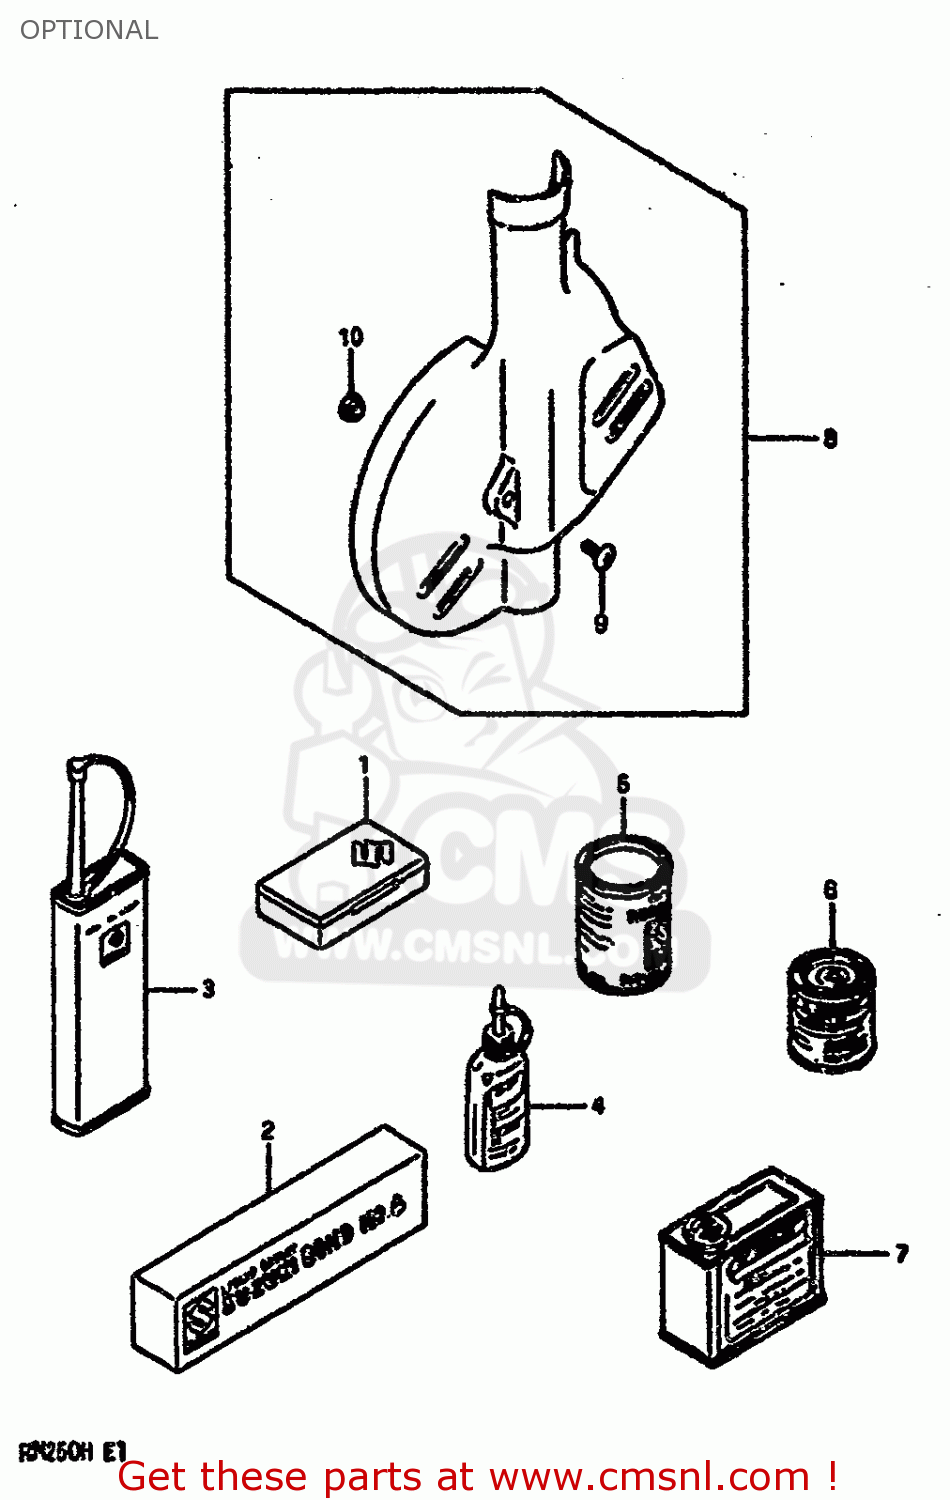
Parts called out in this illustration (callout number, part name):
1	TUBE REPARING TOOL
2	BOND 1104
3	THREAD LOCK NO.1401 CLEAR 200G
4	THREAD LOCK NO
5	GREASE(C)EP2 LITHIUM 150G
6	PAINT (ACCENT BLUE)
7	PAINT (ACCENT BLUE)
8	COVER,FRONT DISC
9	SCREW(8X12)
10	WASHER
